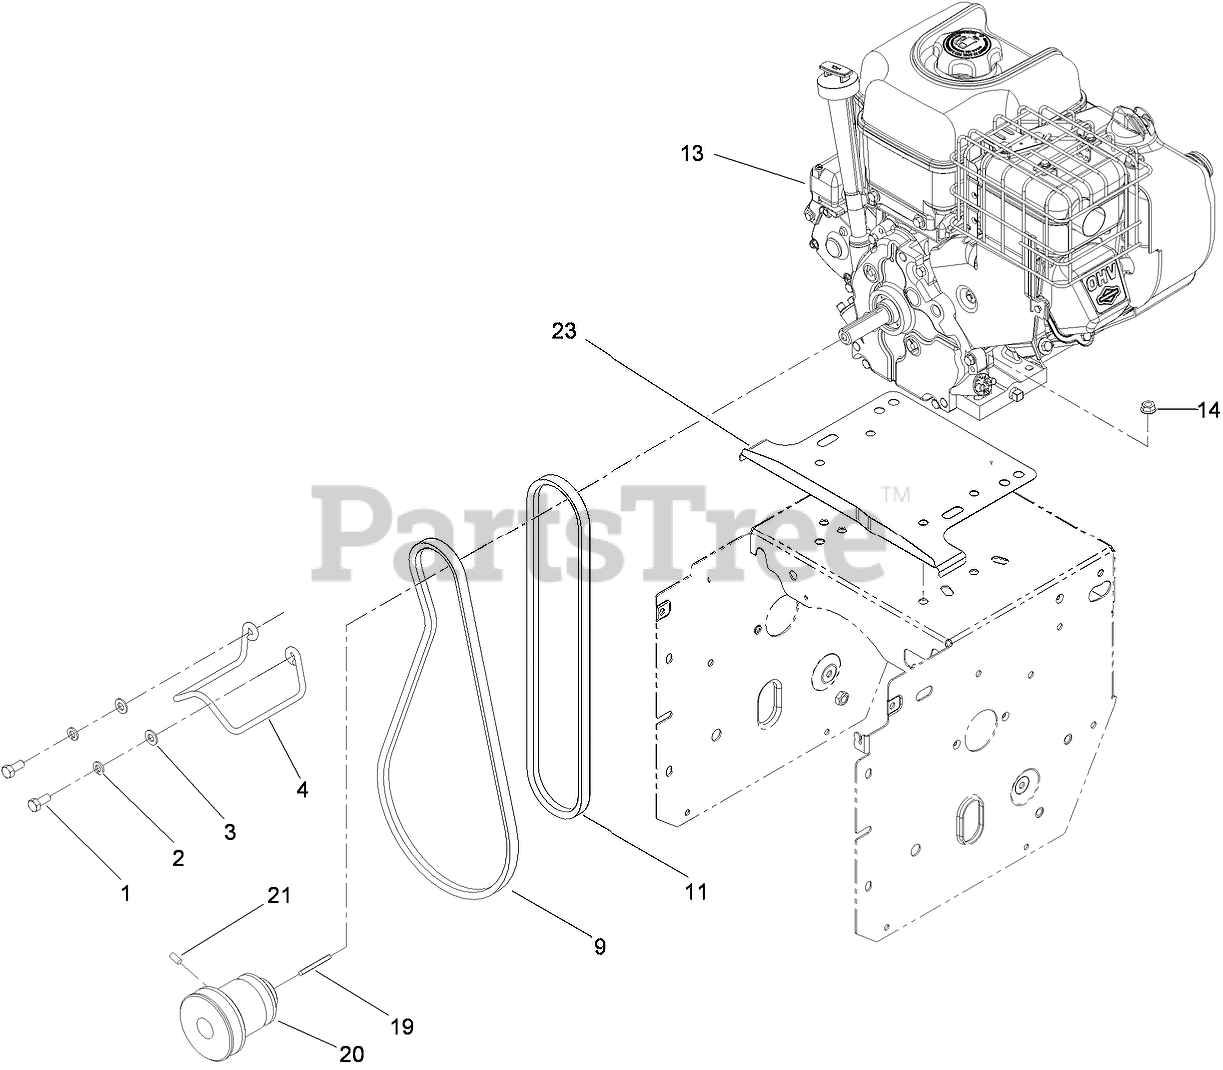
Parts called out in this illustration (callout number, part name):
1	SCREW-HH
2	WASHER-LOCK
3	WASHER-PLAIN
4	GUIDE-BELT
9	BELT-V
11	V BELT-TRACTION
14	NUT-HF
19	KEY-SQUARE
20	PULLEY-ENGINE
21	SCREW-SET, HSH
23	SHIELD-DRIVE
